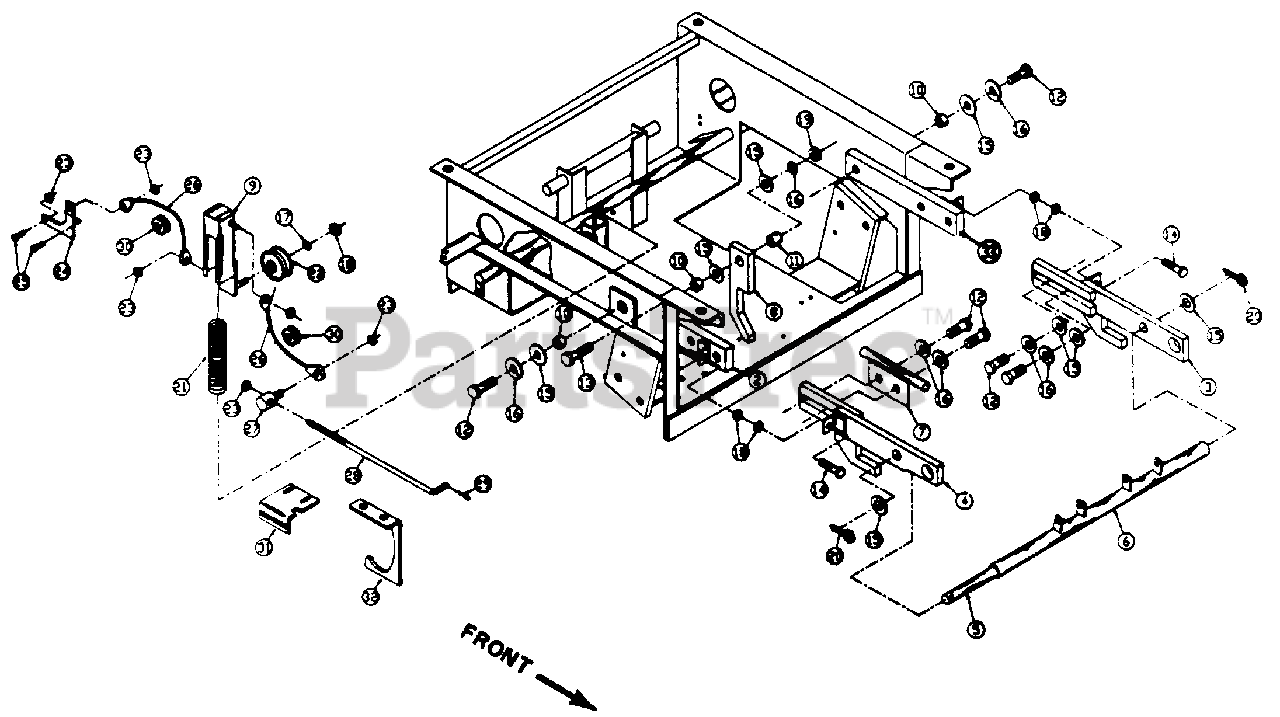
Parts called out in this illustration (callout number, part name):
2	Deck Arm
3	Deck Arm, Front, LH
4	Deck Arm, Front, RH
5	Cross Bar Pin
8	Forward Nose Down Lock
9	Drive Idler Tube
10	Deck Llft Arm Bushlng, Short
11	Deck Llft Aro Bushing
12	Hex Bolt, 112-13 x 1 1/4", GRS
13	Hex Bolt, 1/2-13 x 2 1/4", GRS
14	Hex Tap Bolt, 3/8-16 0 3", GRS
15	Flatwaher, 1/2"
16	Lockw cher, 1/2"
17	Lockwasher, 3/8"
18	Hex Nut, 3/8-16
19	Hex Nut, 1/2-11
20	Cotter Pin, 1/8" x 1"
21	Trans Belt Tightener Spring
22	Idler Pulley, 2 1/4" OD
23	Elastlc Stop Nut, 1/4-20
24	L Brake Linkage
25	Hex Bolt, 1/4-20 x 1", GRS
26	Clutch Brak-Cable
27	Caliper Rod Collar
29	Cotter Pin, 3/32" x 1"
30	Cable Pulley, 1 1/2" OD
31	Engine Retainer Bracket
32	Englne Belt Retainer
33	Deck Arm, LH
